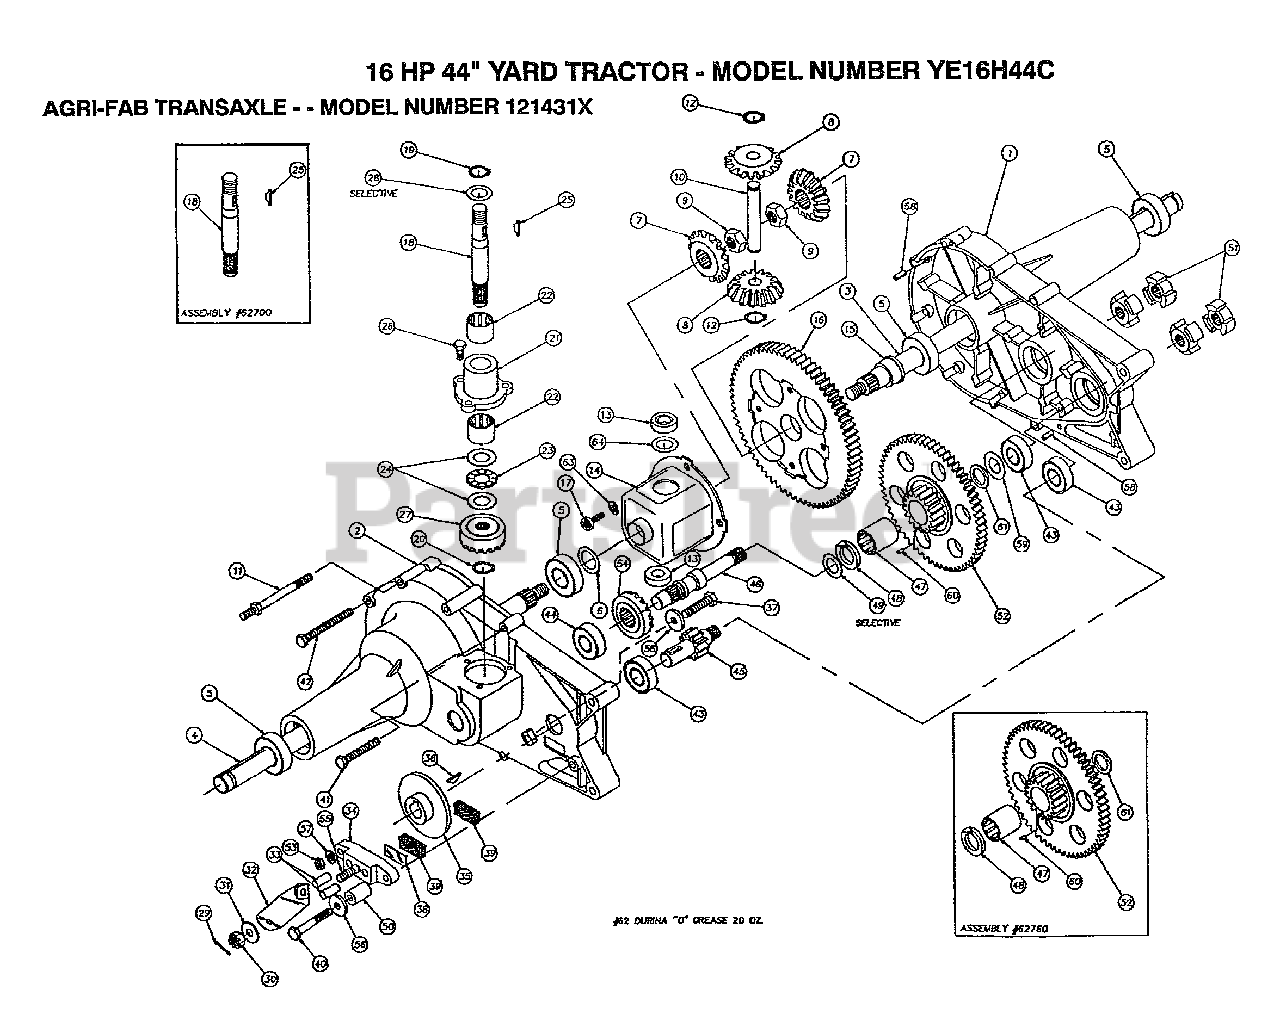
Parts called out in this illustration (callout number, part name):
1	HSG HALF LH-44077
2	HSG HALF RH-44076
3	AXLE LH -44273
4	AXLE RH-44272
5	BEARING.44121.AGR
6	WASHER -44008
7	GEAR MITER -44096
8	GEAR MITER -44097
9	NUT -44133
10	SHAFT CROSS
11	SCREW-STUD -44271
12	SNAP RING -44146
13	"THRUST, BEARING -44128"
14	HOUSING.ASM.DIFF.-62590
15	"FLANGE, BEARING-44129"
16	GEAR
17	BOLT -44126
18	SHAFT INPUT-44270
19	SNAP RING -44145
20	RET RING (44144)
22	"NEEDLE, BEARING 44099"
23	BEARING.NEE.44139
24	WASHER-44109
25	KEY.44136.HYDRO
26	SCREW
28	WASHER -44371
29	PIN COTTER -44101
30	WASHER -44150
31	WASHER FLAT -44130
32	ARM BRAKE 23710
33	PIN BRAKE ACTUATO -44127
34	BRAKE YOKE
35	DISC BRAKE -(44090)
36	KEY -44143
37	SCREW -44277
38	PLATE PUCK -44134
40	SCREW -44300
41	SCREW -44123
42	SCREW -44124
44	"BALL, BEARING -44232"
45	SHAFT PINION 44083
46	SHAFT DRIVE-44080
47	NEEDLE BEARING -44342
48	THRUST.BRONZE -44343
49	WASHER -44371
50	SPACER -23711
51	COUPLING- 44084
52	GEAR.60/17.44523
53	NUT -43178
54	PINION-DR.44079
55	BOLT SQ HD
56	WASHER -44278
57	WASHER -44137
58	PIN ROLL-44269
59	WASHER -44125
60	DOWEL PIN -44346
61	SEAL GREASE -44394
62	WASHER.43177.AGRI
63	ASS'Y GEAR REDUCT
65	GREASE.50416.10OZ
